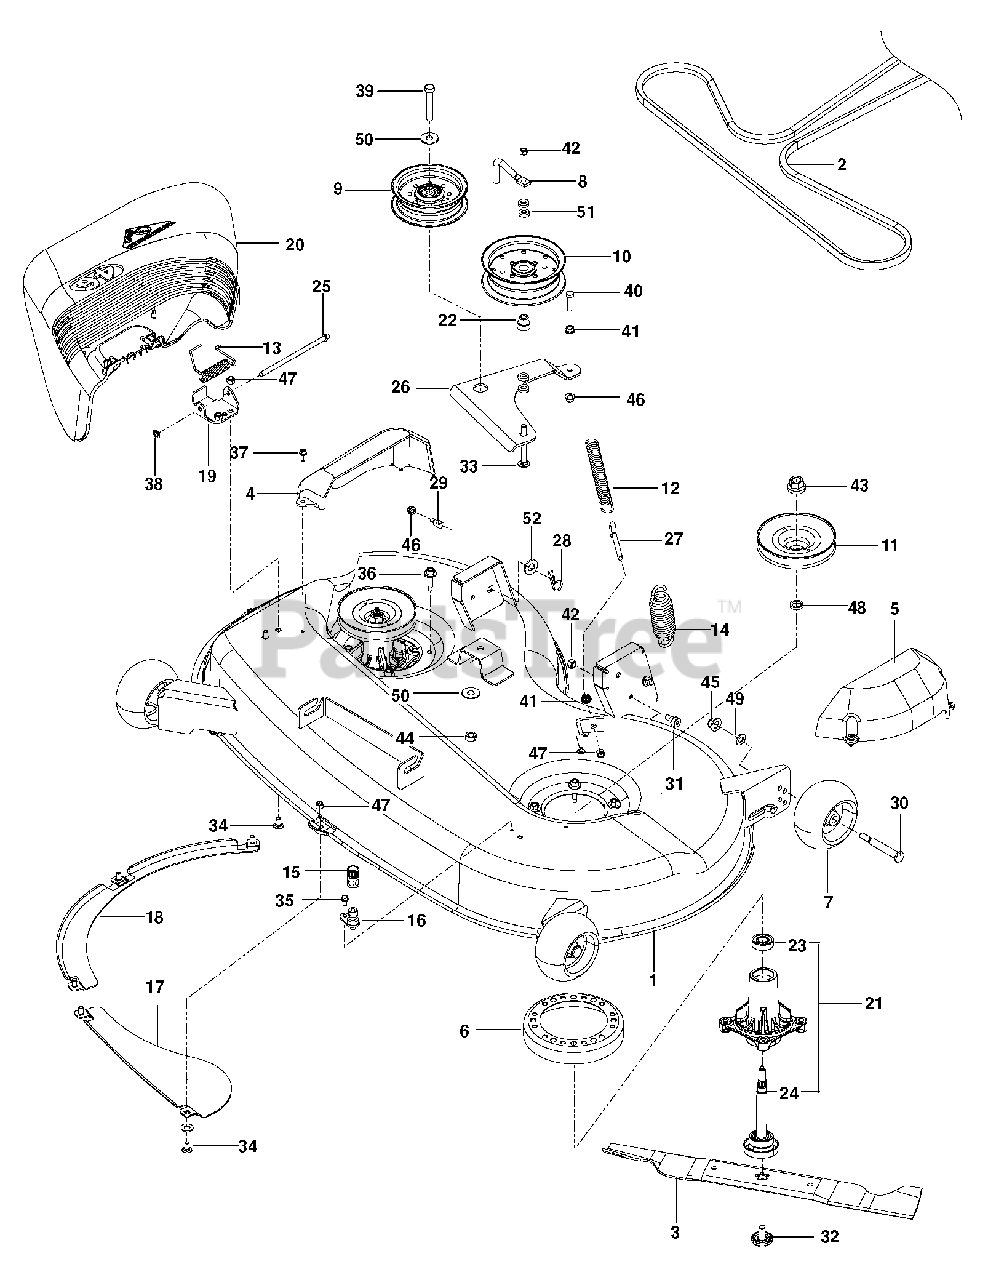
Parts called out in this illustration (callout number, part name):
1	DECK.STAMPED.46".W/DECALS.BLAC
3	BLADE, 46" HI-LIFT
4	COVER.MANDREL.RH.46"
5	COVER.MANDREL.LH.46"
6	STRIPPER.MANDREL.ROUND.BLACK
7	WHEEL. GUAGE RALLY
8	BELT KEEPER 5"
9	PULLEY.IDLER.MWR.STATIONARY.LH
10	PULLEY, IDLER
11	PULLEY, DECK
12	SPRING, DECK BELT
13	TORSION SPRING
14	SPRING
15	COUPLING.QUICK CONNECT
16	PORT.WASHOUT
17	BAFFLE CENTER FRONT
18	BAFFLE FRONT RH
19	BRKT.DEFLECTOR.38"2005+
20	SHIELD.DEFLECTOR.MOWER.46"BLAC
21	MANDREL ASM
22	IDLER BUSHING
24	SHAFT ASM W/LOWER BEARING
25	ROD, HINGE
26	ARM, IDLER BLK
27	EYE BOLT 5/16 X 3.50
28	HAIRPIN #4
29	STUD.FASTNER.W/ANTI-ROTATE
30	BOLT, SHOULDER
31	SB 3/8-16 X 3/8 SKT HD ZD
32	BOLT.WASHER.ASM.7/16-2
33	CARRIAGE BOLT 3/8-16 X
34	BOLT
35	SCREW #10 X 1/2 SELF TAPPING
36	SCREW, WASHER HEAD
37	SCREW- 1/4-20 X 5/8
38	NUT PUSH M
39	BOLT 7/16-14 X 2-1/2 GR 5 ZD
40	HCS 5/16C X 1 1/4
41	NUT 5/16C WHIZ
42	NUT HEX 3/8-16 NYLON, THIN
43	NUT.FLANGE.LOCK.TOP
44	7/16-14 HEX NUT W/NYL RING ZD
45	NUT
46	5/16-18 NYLOC FLANGE NUT
47	NUT.71038.31-18.HEX.NYLOCK
48	WASHER.SPACER.MANDREL
50	WASHER 7/16 FLAT ZD
51	WASHER 3/8 X 3/4 X .187 TK
52	WASHER
